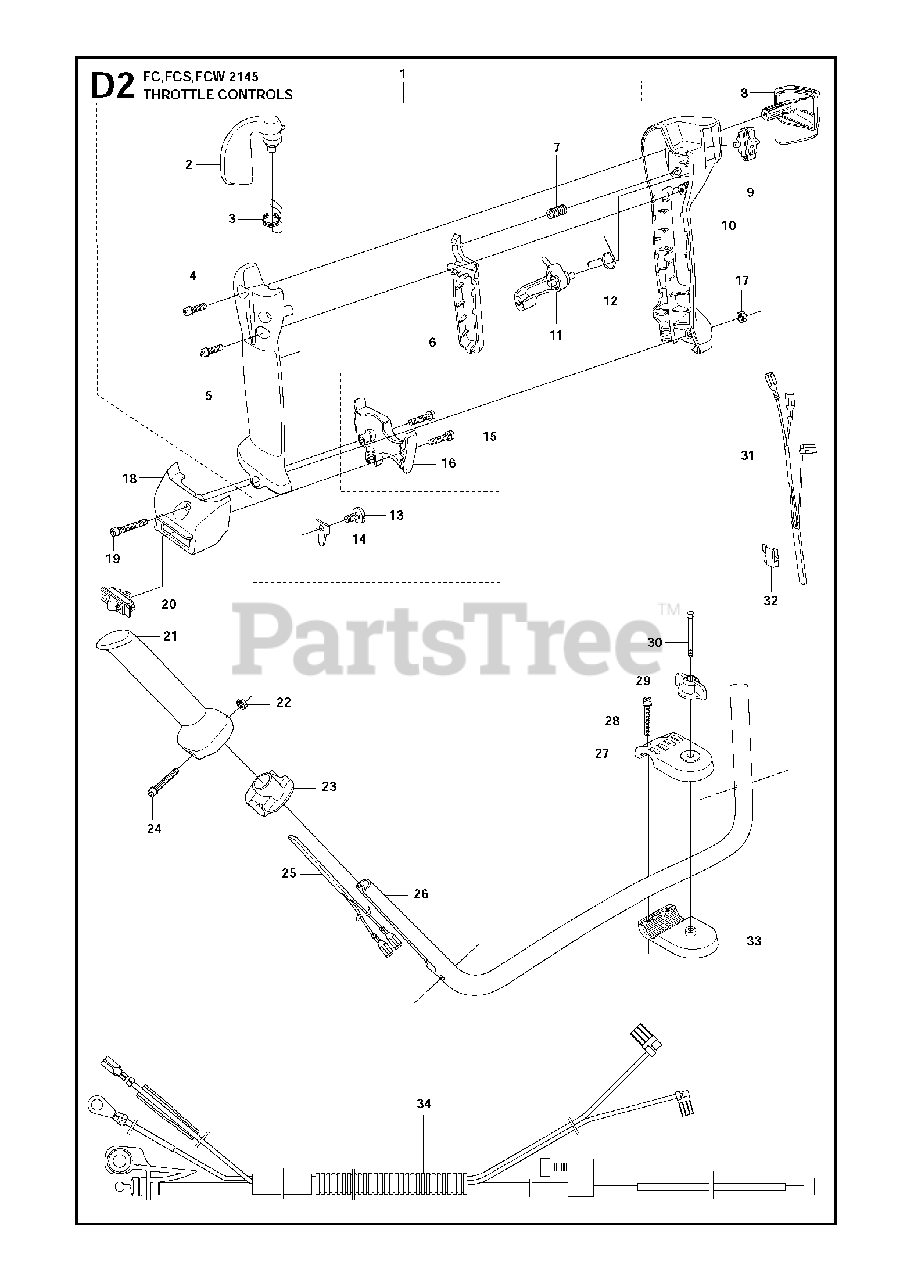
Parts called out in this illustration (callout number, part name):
3	RP SPRING
4	SCREW
7	SPRING
9	STOP BUTTON
10	HANDLE HALF RIGHT
11	LEVER
12	SPRING
13	SCREW
14	HOLDER
15	SCREW
17	NUT M6M M5
19	SCREW
20	SWITCH (G)
22	NUT M6M M5
23	HANDLE FASTENER
25	HEATING ELEMENT
26	RP HANDLE
26	%HANDLE
27	HANDLE BRACKET
30	SCREW 6X70
31	HEATING ELEMENT
32	HOLDER
33	HANDLE BRACKET
34	RP WIRING ASSY
34	WIRING ASSY
